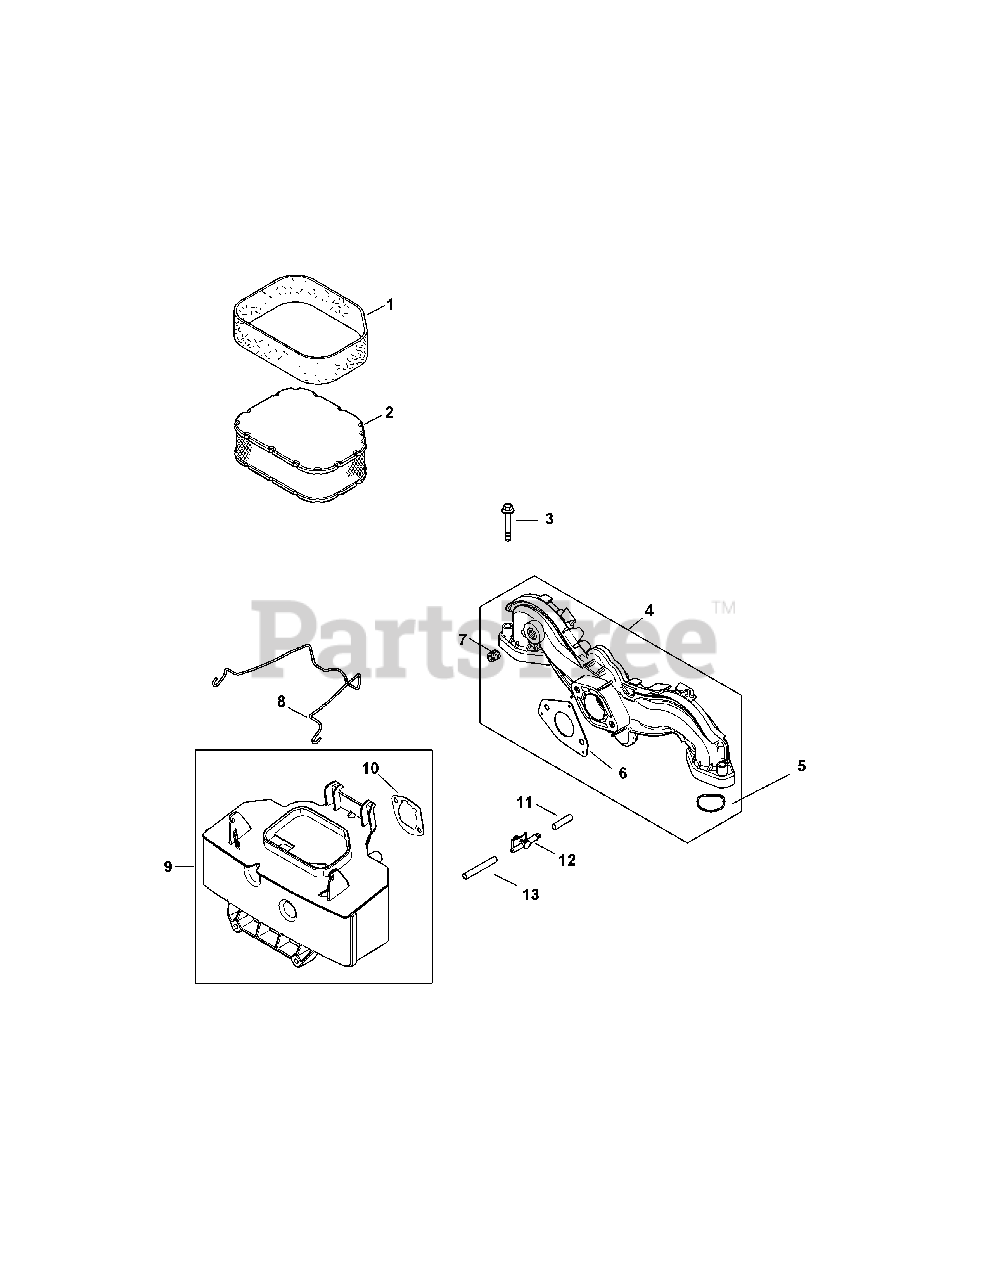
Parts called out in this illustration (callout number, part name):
1	Pre-Cleaner, Element
2	Element, Air Filter
3	Screw, Flg M6X1.0X40
4	Kit, Intake Manifold
5	O-Ring, Intake Port
6	Gasket, Carburetor
7	Plug, Ctsk Pipe 1/8''
8	Latch, Air Cleaner Element
9	Base, Air Cleaner
10	Gasket, Air Cleaner Base
12	Connector, Evaporative
13	Hose, Evaporative, 20''
